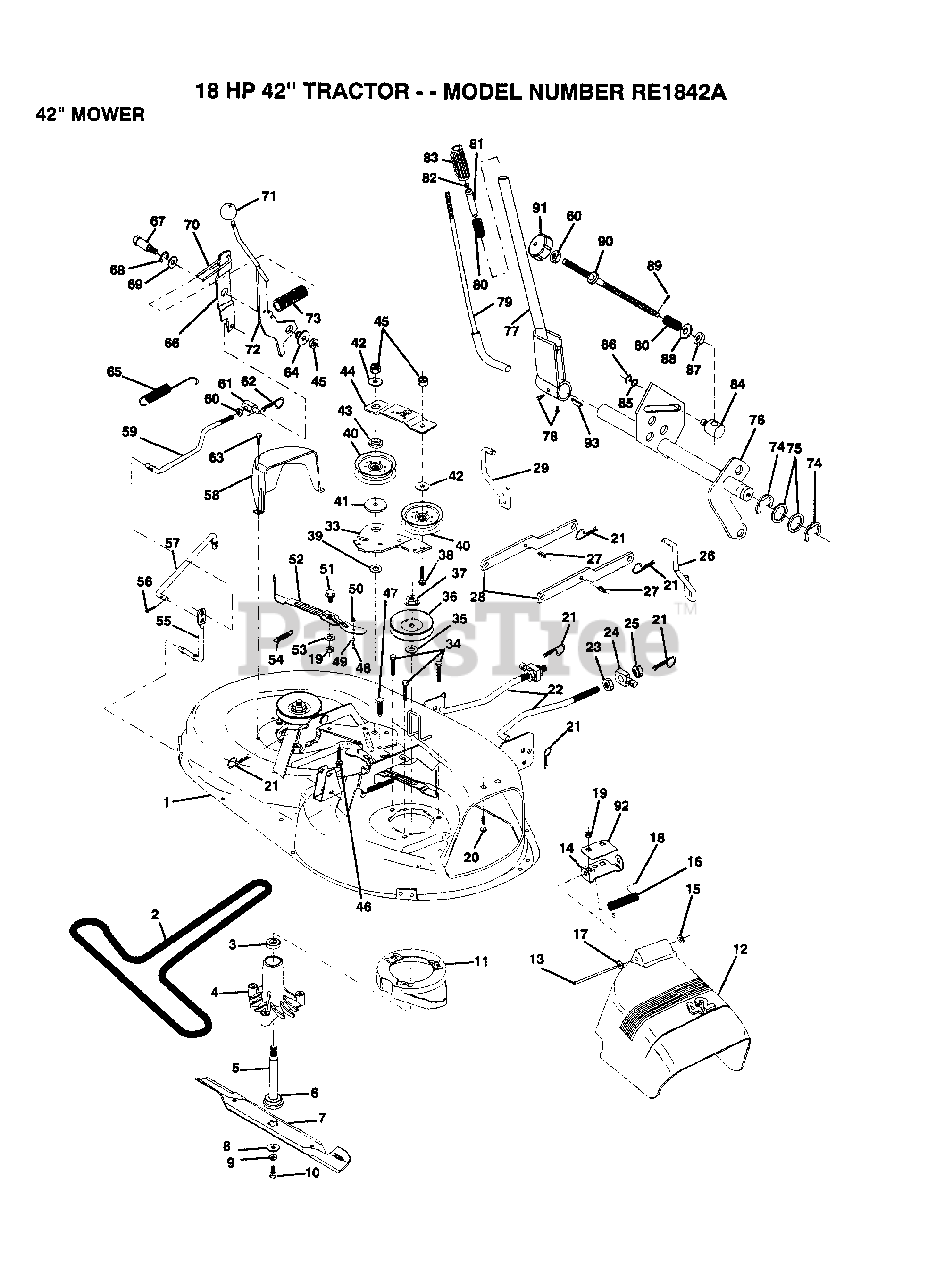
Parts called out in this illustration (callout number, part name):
2	BELT-V.92.4.MWR
3	BEARING
4	HSG ASM MANDREL
6	BEARING.BALL
8	WASHER BLADE
10	BLADE BOLT
12	DEFLECTOR.SHIELD
13	HINGE ROD
14	DEFLECTOR BRKT
15	NUT PUSH M
16	SPRING TORSION
17	WASHER
18	CAP-SLEEVE LT
20	BOLT
22	LINK.FRONT
23	NUT
24	TRUNION
25	NUT.LK.W/WSH.1/2.
26	LIFT LINK RH
27	SPRING PIN
29	LINK LIFT LH
33	IDLER ARM
35	WASHER
38	BOLT
39	HARDENED WASHER
40	FLAT IDLER PULLEY
41	SPACER RETAINER
42	WASHER GT
43	RETAINER SPACER
44	IDLER ARM STIFF
46	BOLT CARRIAGE
47	XMAS TREE FASTNER
48	SHOULDER BOLT
50	LOCKNUT
52	BRAKE PAD ARM ASM
53	HARD SMALL WASHER
54	SPRING EXTENSION
55	PIVOT ROD
57	CLUTCH ROD SECOND
60	NUT
61	TRUNION
62	RETAINER M
63	SCREW LT
64	BUSHING
65	RETURN SPRING
66	CLUTCH ARM SECOND
67	SHOULDER BOLT
68	RING
69	WASHER
70	SPRING KEEPER
74	E-RING
75	WASHER
79	ROD ASS'Y LEVER
80	SPRING T
83	GRIP
84	TRUNION LT
85	WASHER
86	KLIP RING
87	NUT T
88	WASHER
90	ROD LIFT LT
92	STIFFENER BRKT
